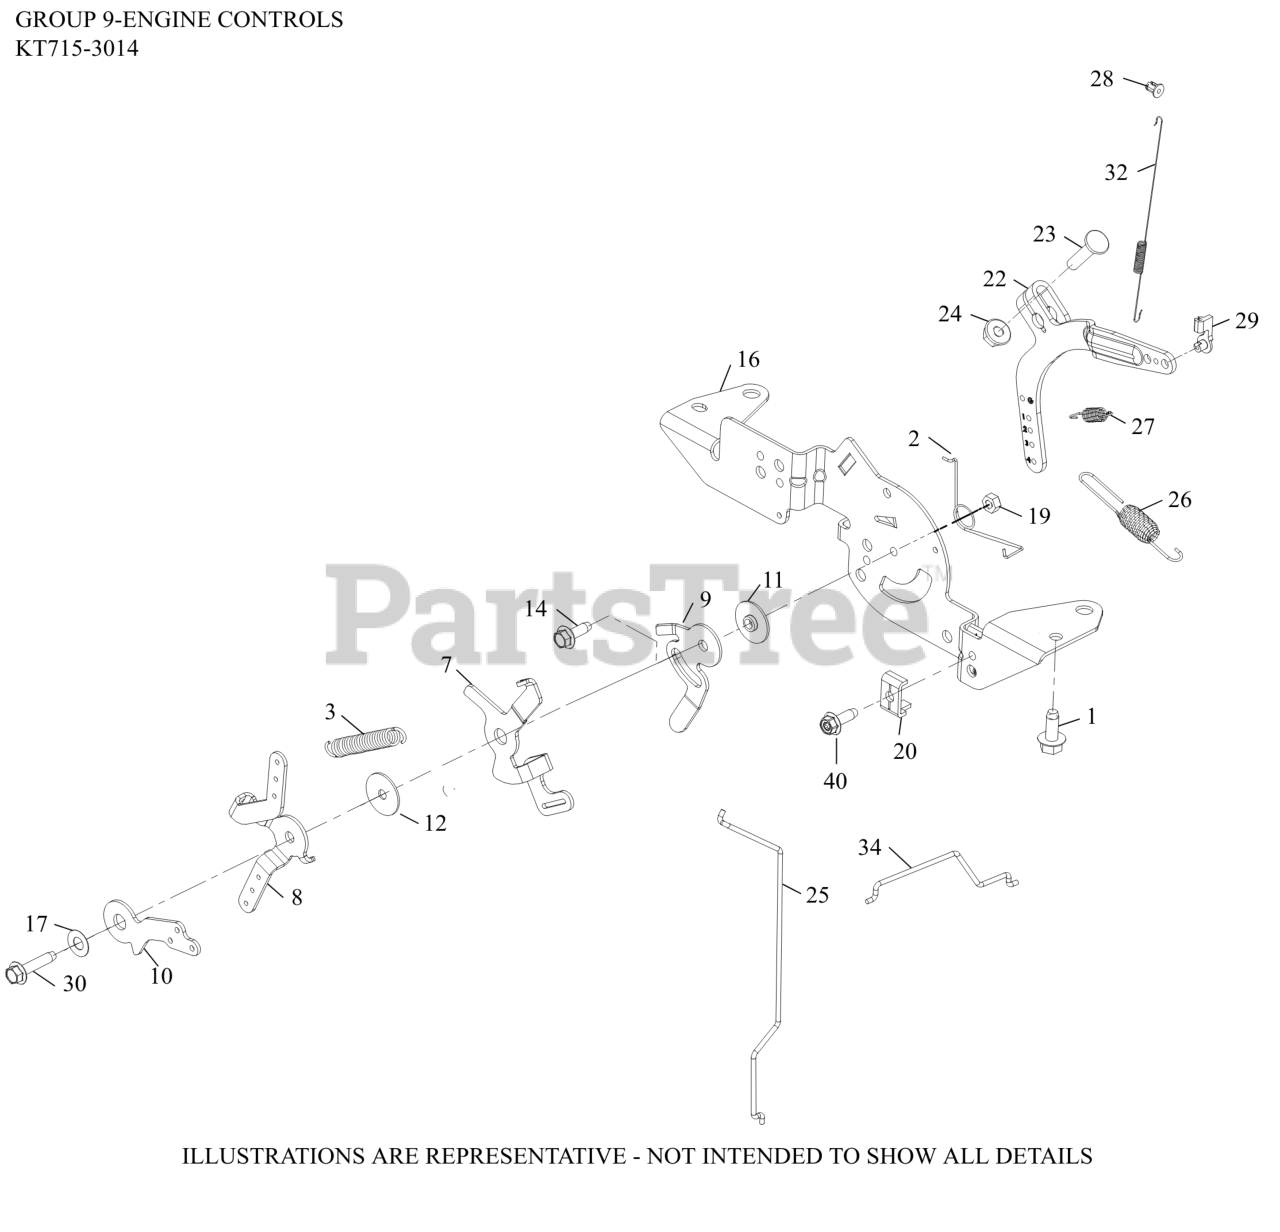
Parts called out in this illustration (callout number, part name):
1	SCREW, THREAD FORMING
2	SPRING, CHOKE RETURN
3	SPRING, SPEED CONTROL
7	LEVER, GOVERNOR SPRING
8	LEVER, SPEED CONTROL-USE 32 090 26-S
9	LEVER, SPEED SETTING
10	LEVER, CHOKE-DISCONTINUED
11	SPACER, CONTROL ASSEMBLY
12	WASHER, FLAT 5.5 MM
14	SCREW, THREAD FORMING
16	BRACKET, SPEED CONTROL
17	WASHER, SPRING 1/4"
19	NUT, LOCK M5X.8
20	CLAMP, CABLE-(#2523753S)
22	LEVER, GOVERNOR - (#2409069S)
23	BOLT, RD HD SQ NECK M6X1.0X25
24	NUT, FLG M6X1.0
25	LINKAGE, CHOKE
26	SPRING, GOVERNOR (ORANGE)
27	SPRING, GOVERNED IDLE
28	BUSHING, LINKAGE RETAINING
29	BUSHING, THROTTLE LINKAGE
30	SCREW, THREAD FORMING-USE 25 086 472-S
32	SPRING, LINKAGE
34	LINKAGE, THROTTLE
40	SCREW, THREAD FORMING
